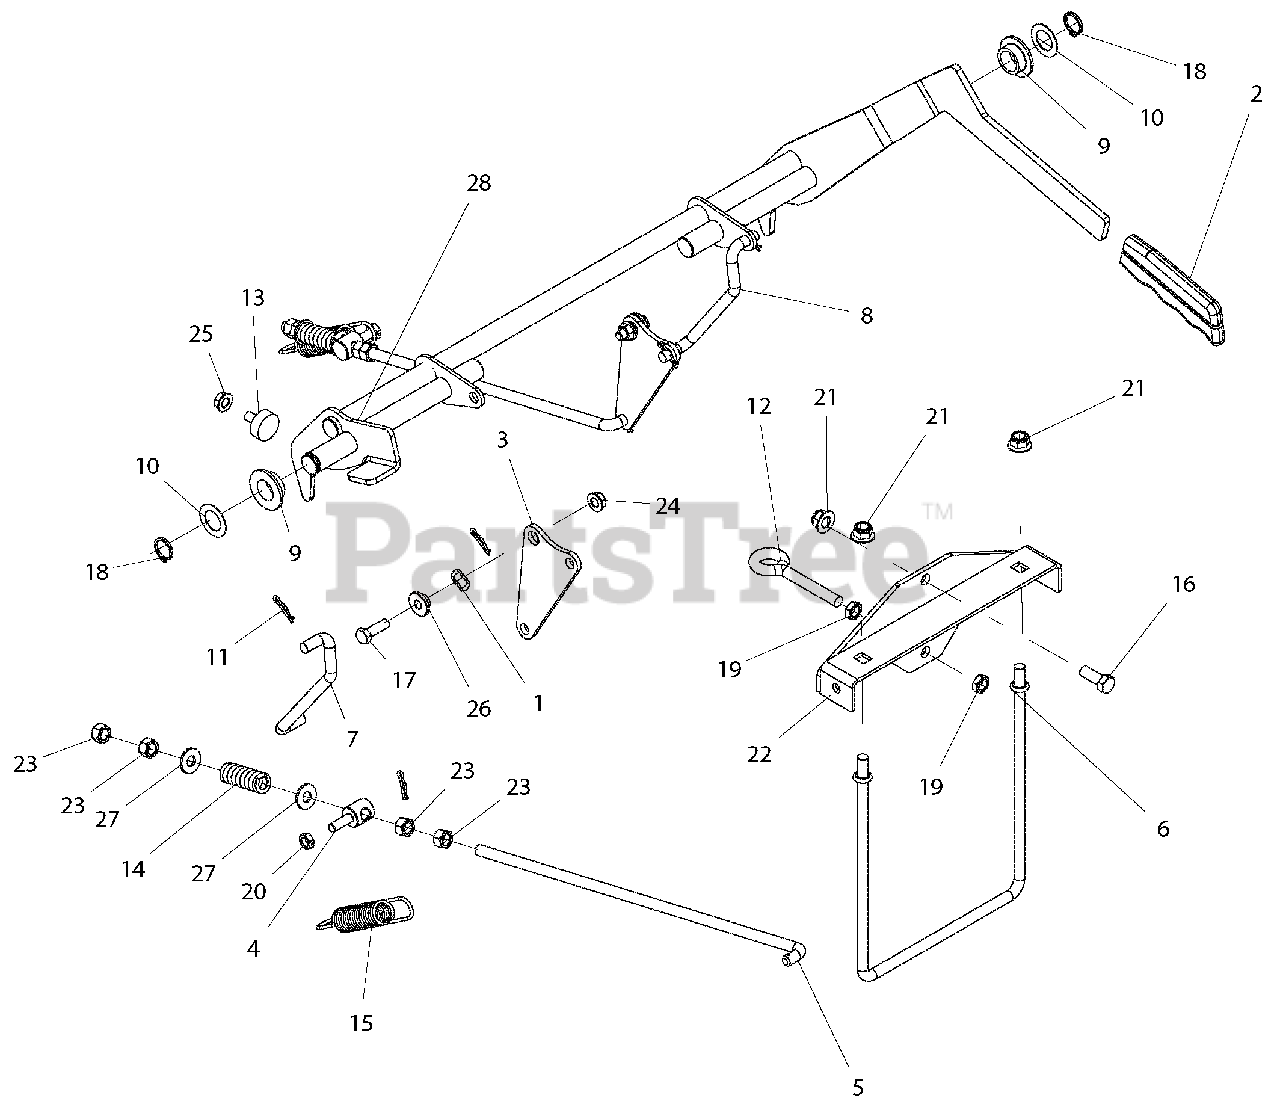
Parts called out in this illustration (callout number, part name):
1	WAVE WASHER .531X.781X.125 FH
2	GRIP, PARKING BRAKE (YELLOW)
3	PLATE, BRAKE PIVOT-BLACK
4	TRUNNION, .31-18
5	ROD, BRAKE ADJ.
6	ROD, BRAKE MTG
7	LINKAGE, RH BRAKE ACTUATING
8	LINKAGE, LH BRAKE ACTUATING
9	BSHG, FLANGE .762 X 1.48 X .44 NYLON
10	WSHR-HDND-THRST
11	PIN-HAIR, ENDRIES #25 YWZC
12	BOLT, EYE .375-16
13	BUMPER, RUBBER
14	SPRG, COMPRESSION
15	SPRG, EXTENSION
16	BLT-HEX .38-16X1.00 GR5 YWZC
17	BLT-HEX .31-18X1.00 GR5 YWZC
18	RG-RTNG-EXT .750x.078
19	NUT, JAM .375-16 YWZC
20	@NUT-LK-CTR-JAM .31-18 YWZC
21	NUT-LK-NYL-FLG .38-16 YWZC
22	WMT, SPRING ANCHOR BRKT-BLACK
23	NUT-HEX .38-16 YWZC
24	NUT, LK-TOP-FLG .312-18 YWZC
25	@NUT-SPNLK-FLG .312-18 YWZC
26	BSHG, FLG .32X.500.344X.880
27	WSHR-FL-STL.38X.875X.083 YWZC
28	WLDMT, PARKING BRAKE LEVER
